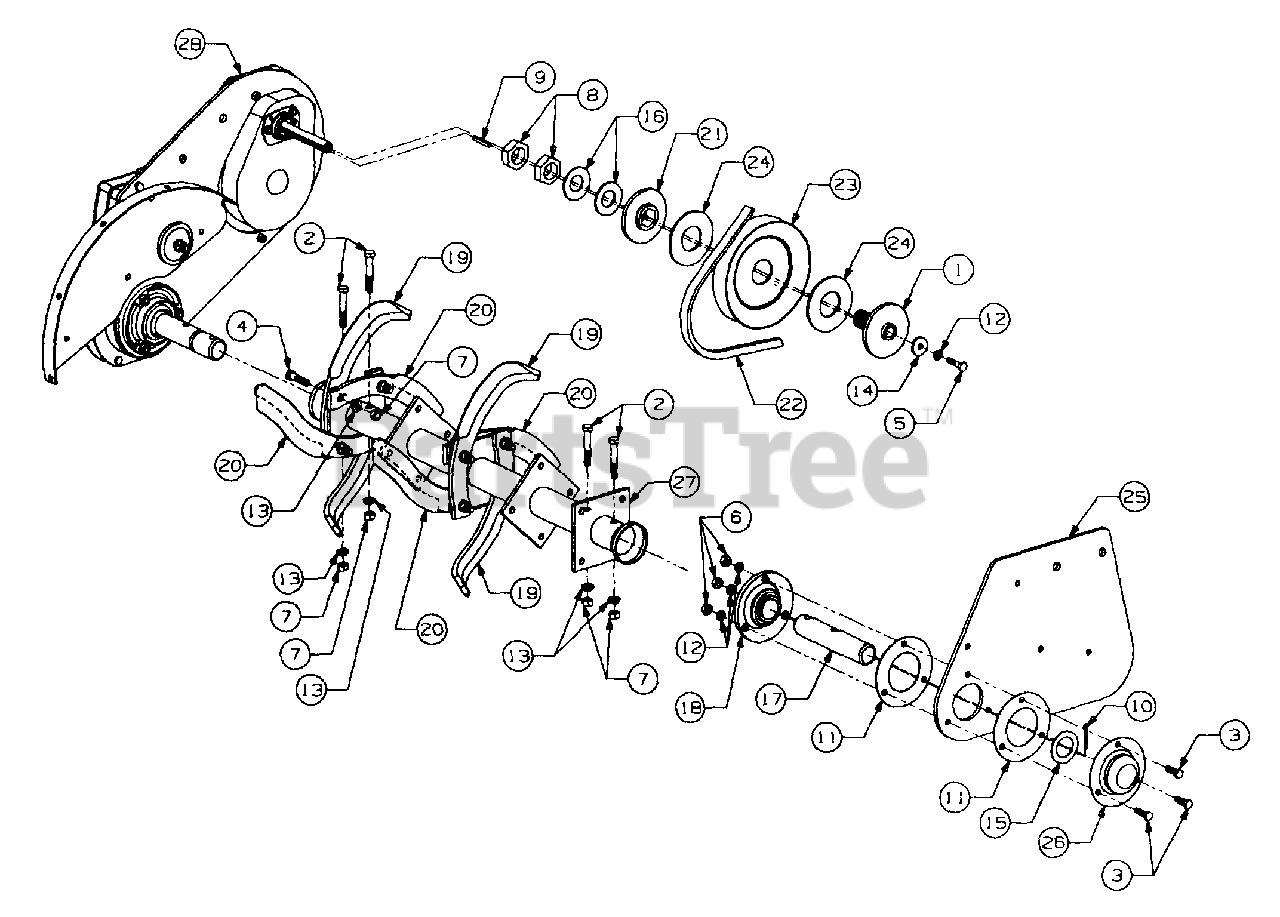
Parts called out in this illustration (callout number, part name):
1	Hub Assy, Friction Disc
2	Screw, Hex Cap, 3/8-24 X 2.25 Lg
3	Screw, Hex Cap, 5/16-18 X 1.0 Lg
4	Screw, Hex Cap, 3/8-24 X 1.50 Lg GR5
5	Screw, Hex Cap, 5/16-18 X 1.25 Lg GR5
6	Nut, Hex Center Lock, 5/16-18
7	Nut, Hex 3/8-24
8	Nut, Hex Jam, 1-14
9	Key, 3/16 Sq X 1.5 Lg
10	Pin, Cotter, 1/8 Dia X 1.25 Lg
11	Gasket, Bearing Hsg
12	Washer, Lock, 5/16
13	Washer, Lock, 3/8 H.D.
14	Washer, Flat, .344 X 1.125 X .125 Thk
15	Washer, Flat, 1.28 X 2.0 X .06 Thk
16	Washer, Spring Bell, 1.0 X 2.0 X .084 Thk
17	Shaft, RH Tine
18	Housing, Bearing
21	Hub, Floating
22	Belt, B-Section X 191 Lg
23	Pulley, Tiller Drive
24	Disc, Friction
